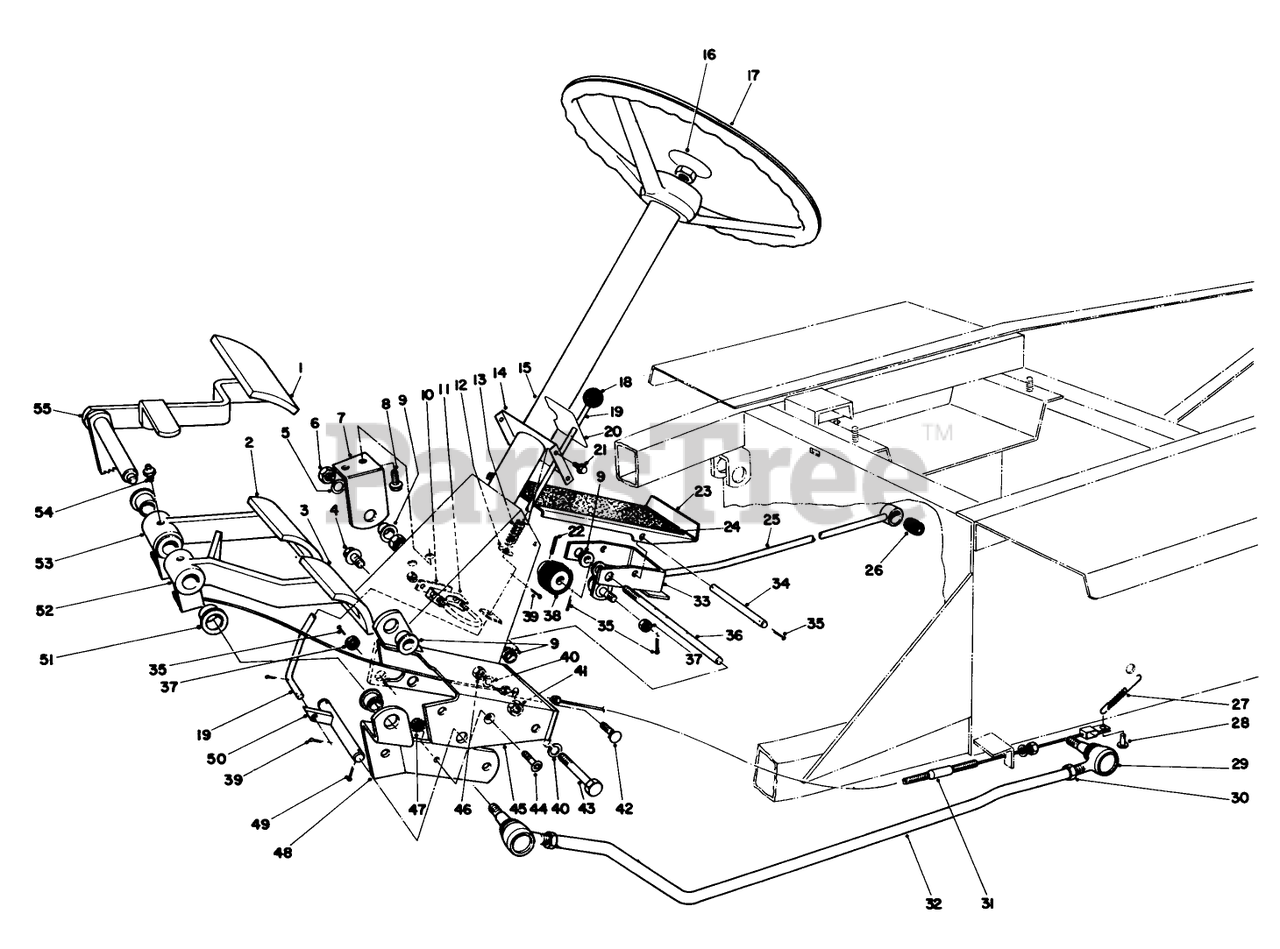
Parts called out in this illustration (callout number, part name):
1	PAD-BRAKE
2	PAD-TURN, RIGHT
3	PAD-TURN, LEFT
4	SCREW-HHF
5	WASHER-FLAT
6	NUT-JAM
7	Mount-RH Pedal
8	SCREW-HWHTF
9	BUSHING-FLANGE
10	GEAR CLIP SPACER
11	MUFFLER CLAMP
12	WASHER-FLAT
13	Spring
14	STRG COLUMN SUPT R
15	STEERING GEAR ASM,GM72 PRE 1988
16	STEERING WHEEL CAP
17	STEERING WHEEL
19	BRAKE LATCH ROD B
20	PARKING BRAKE DECAL
21	SCREW-HWH
22	PIN-SPRING
23	TRACTION PEDAL R
24	TRACTION PEDAL PAD
25	PUMP CONTROL TUBE WA
26	BUSHING-RUBBER
27	SPRING-EXTENSION
28	PIN-CLEVIS
29	Socket Ass-y. (Incl. Ref. #37)
30	NUT-JAM
31	LH BRAKE CABLE ASM
32	FRT STRG TUBE PP
33	Pivot Bracket (Incl. Ref. #9)
34	TRACT PEDAL PIN
35	PIN-COTTER
36	TRACT PEDAL SHAFT
37	NUT-SLOTTED
38	FRICTION WHEEL ASM
39	PIN-COTTER
40	WASHER-LOCK
41	NUT-LOCK, SIDE
42	SCREW-CARR
43	SCREW-HH
44	SCREW-HSFH
45	Brake Mount
46	NUT-HEX
47	NUT-KEPS
48	Brake Pivot Shaft Mount
49	PIN-COTTER
50	Brake Latch Shaft
51	BUSHING-FLANGE
52	Brake Pedal L.H. (Incl. Ref. #51)
53	Brake Pedal R.H. (Incl. Ref. #51)
54	FITTING-GREASE
55	Pedal-Parking Bake
